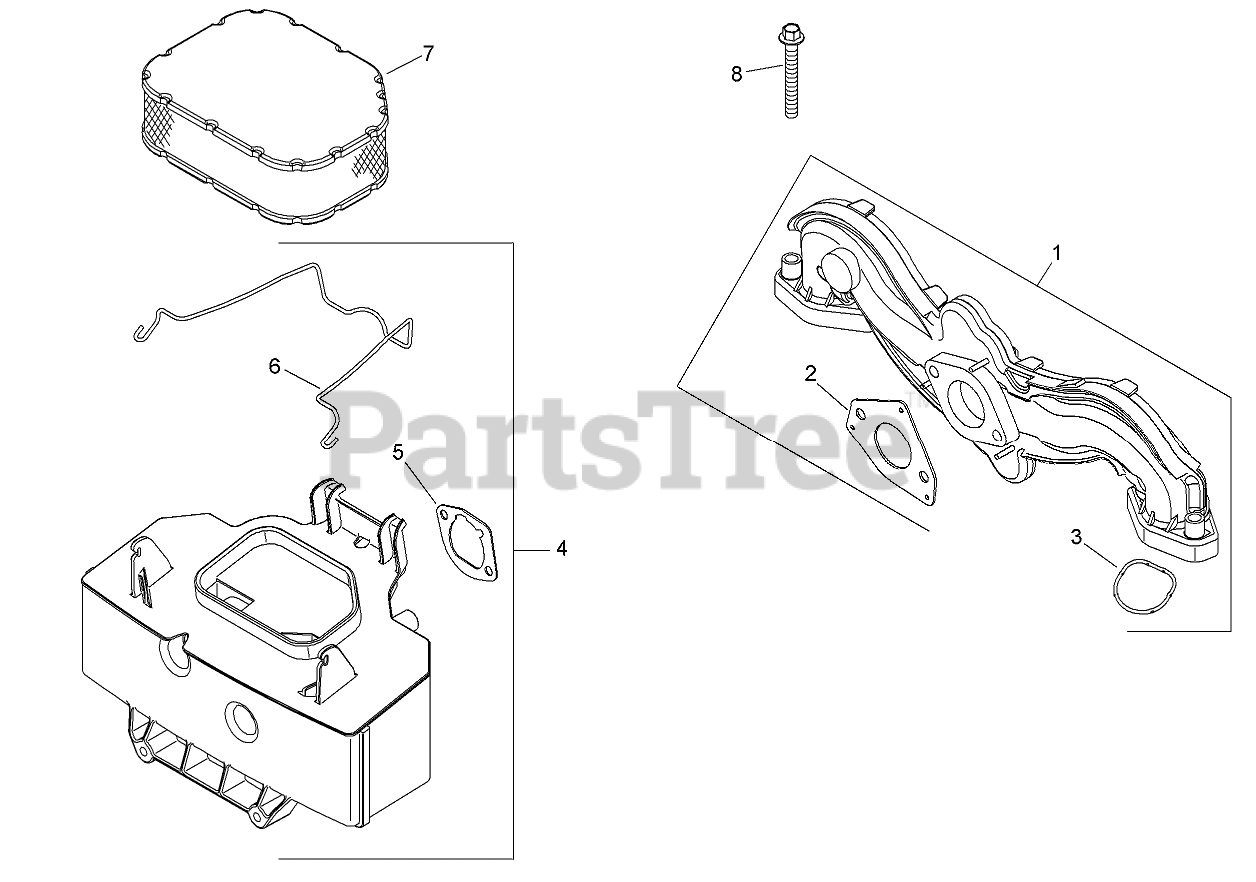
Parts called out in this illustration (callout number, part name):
1	Manifold-Intake
2	GASKET-CARBURETOR
3	O-RING
4	AIR CLEANER BASE KIT
5	GASKET-BASE, AIR CLEANER
6	LATCH-ELEMENT, AIR CLEANER
7	ELEMENT-FILTER, AIR
8	SCREW-FLANGE (M6X1.0X40)
